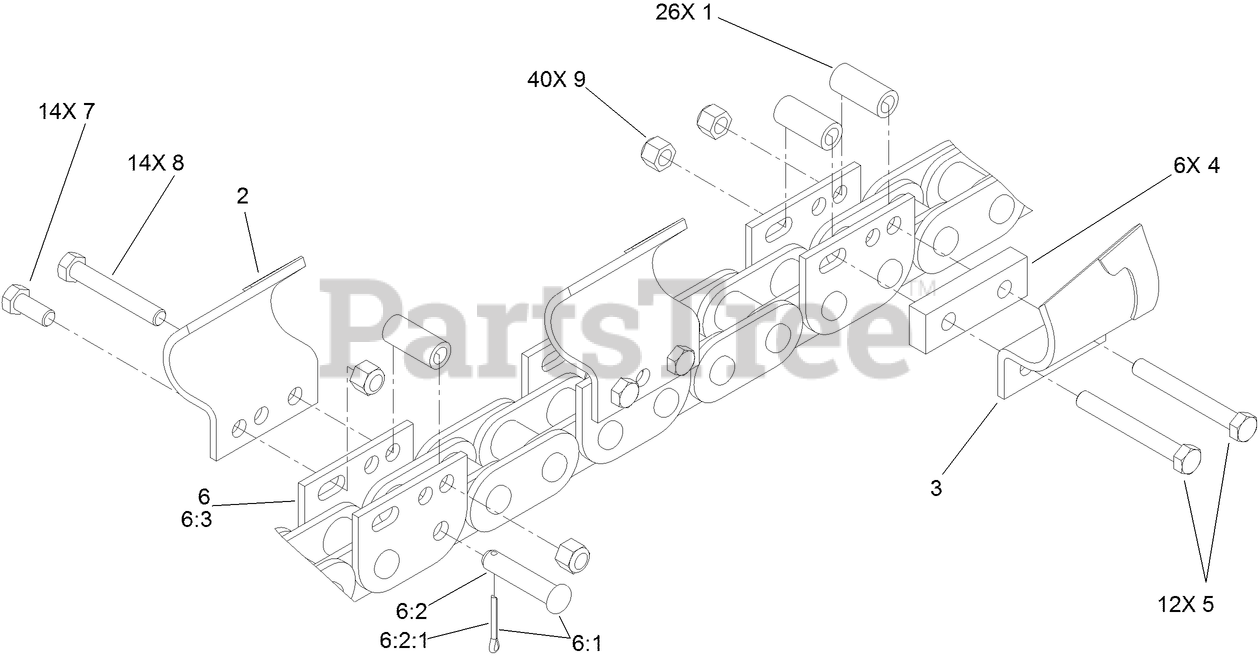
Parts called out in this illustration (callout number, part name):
1	SPACER-TUBE
2	TOOTH-SOIL, LH
3	TOOTH-SOIL, RH
4	SPACER-CUT, 5 INCH
5	SCREW-HH
6	CHAIN-BARE, 20 STATION
6:1	PIN-CONNECTING
6:2	PIN-CONNECTING (61MM)
6:2:1	PIN-COTTER
6:3	LINK REPAIR KIT
8	SCREW-HH
9	NUT-HEX
